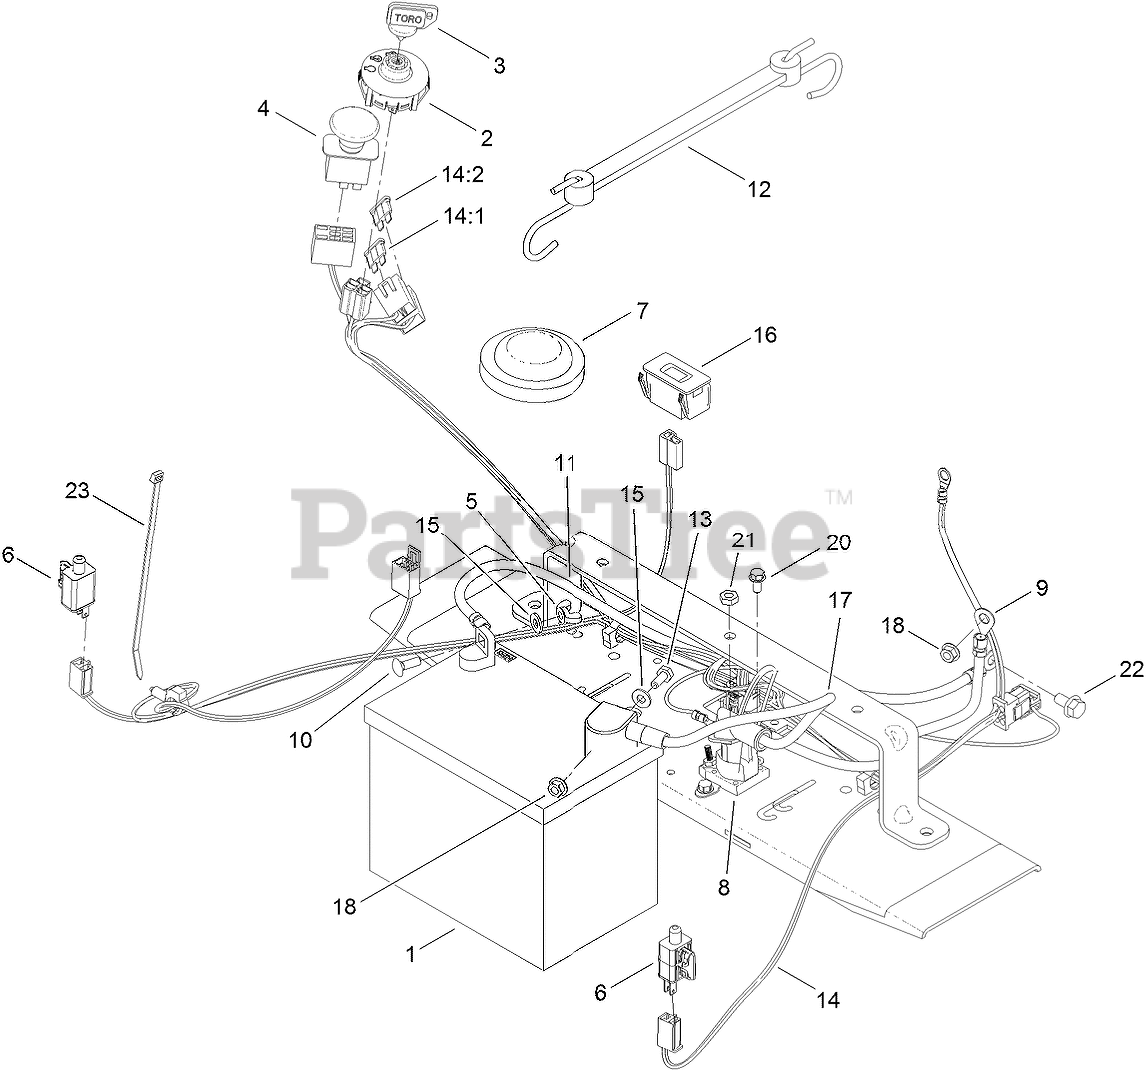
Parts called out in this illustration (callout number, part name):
1	BATTERY
2	SWITCH-IGNITION
3	KEY-IGNITION
4	SWITCH-PTO
5	NUT-WING
6	SWITCH
7	SWITCH-SEAT
8	SOLENOID
9	CABLE-BATTERY, RED
10	BOLT-CARR
11	CABLE-BATTERY, BLACK
12	HOLDDOWN-BATTERY
13	SCREW-HH
14	HARNESS-WIRE
14:1	FUSE-BLADE, 30 AMP
14:2	FUSE-BLADE, 25 AMP
15	WASHER-FLAT
16	HOURMETER
17	CABLE-BATTERY, RED
18	NUT-HF
20	SCREW-HWH
21	NUT-JAM
22	SCREW-HHF
23	TIE-CABLE
